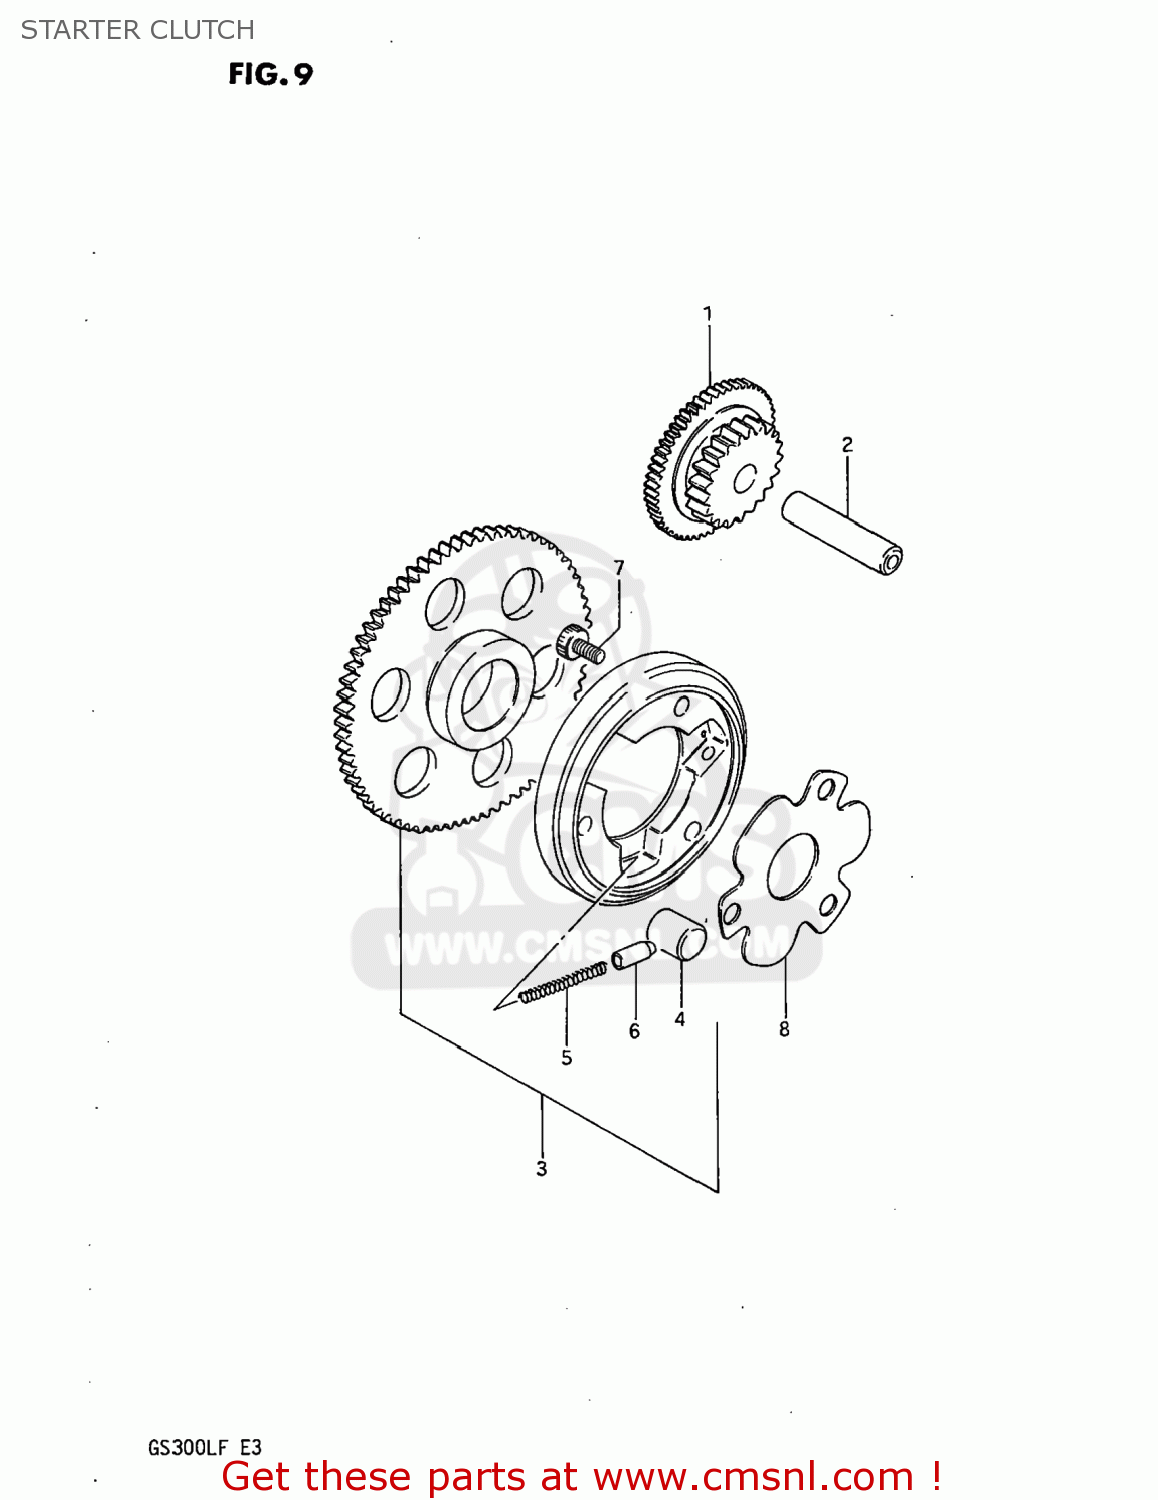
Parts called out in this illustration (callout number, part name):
1	GEAR,STARTER IDLE
2	PIN(7.4X13X40)
3	CLUTCH SET,STARTER
4	ROLLER(15X13)
5	SPRING
6	PIECE,PUSH
7	BOLT
8	SHIM,STARTER CLUTCH HUB
